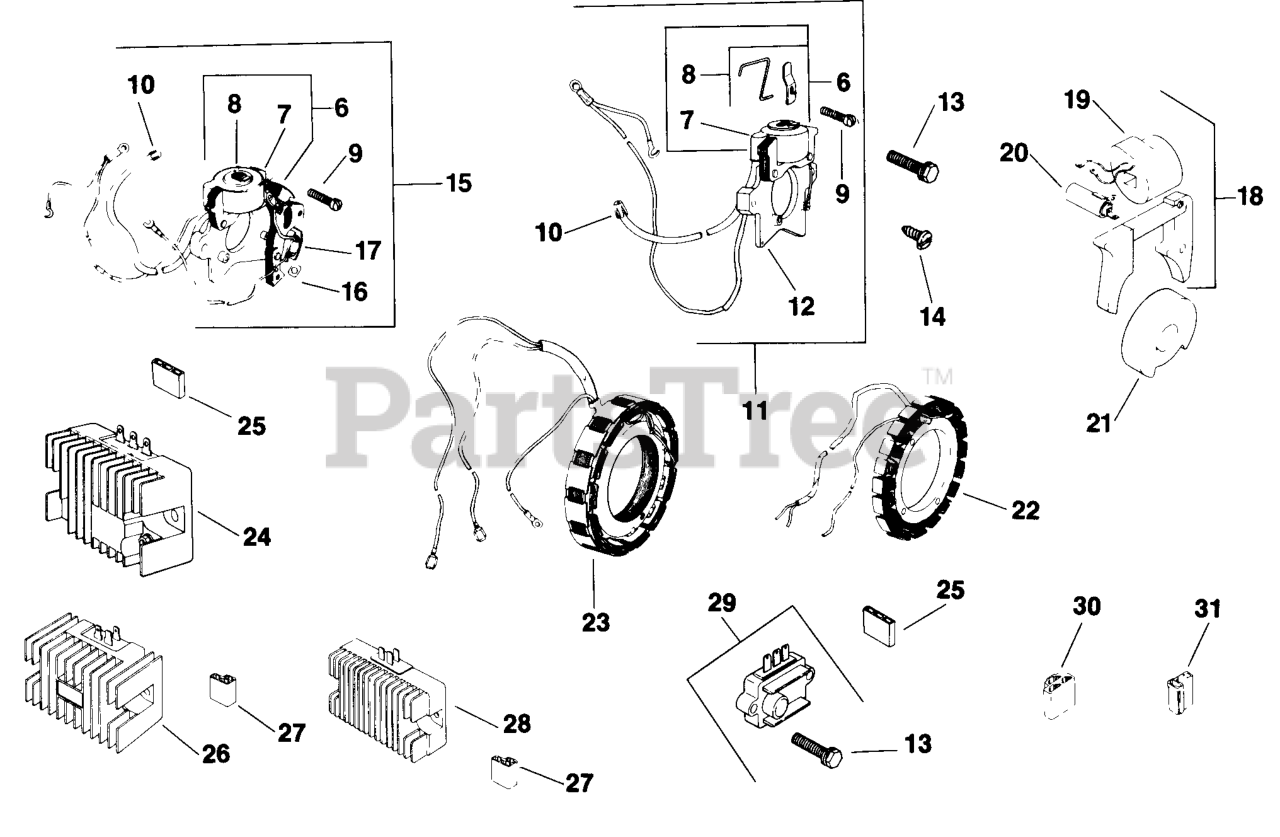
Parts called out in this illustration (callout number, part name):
13	SCREW, SEMS 1/4-20X5/8" USE 25 086 539-S
26	REGULATOR/RECTIFIER (KM)-USE 25 403 22-S
27	CONNECTOR - DISCONTINUED
